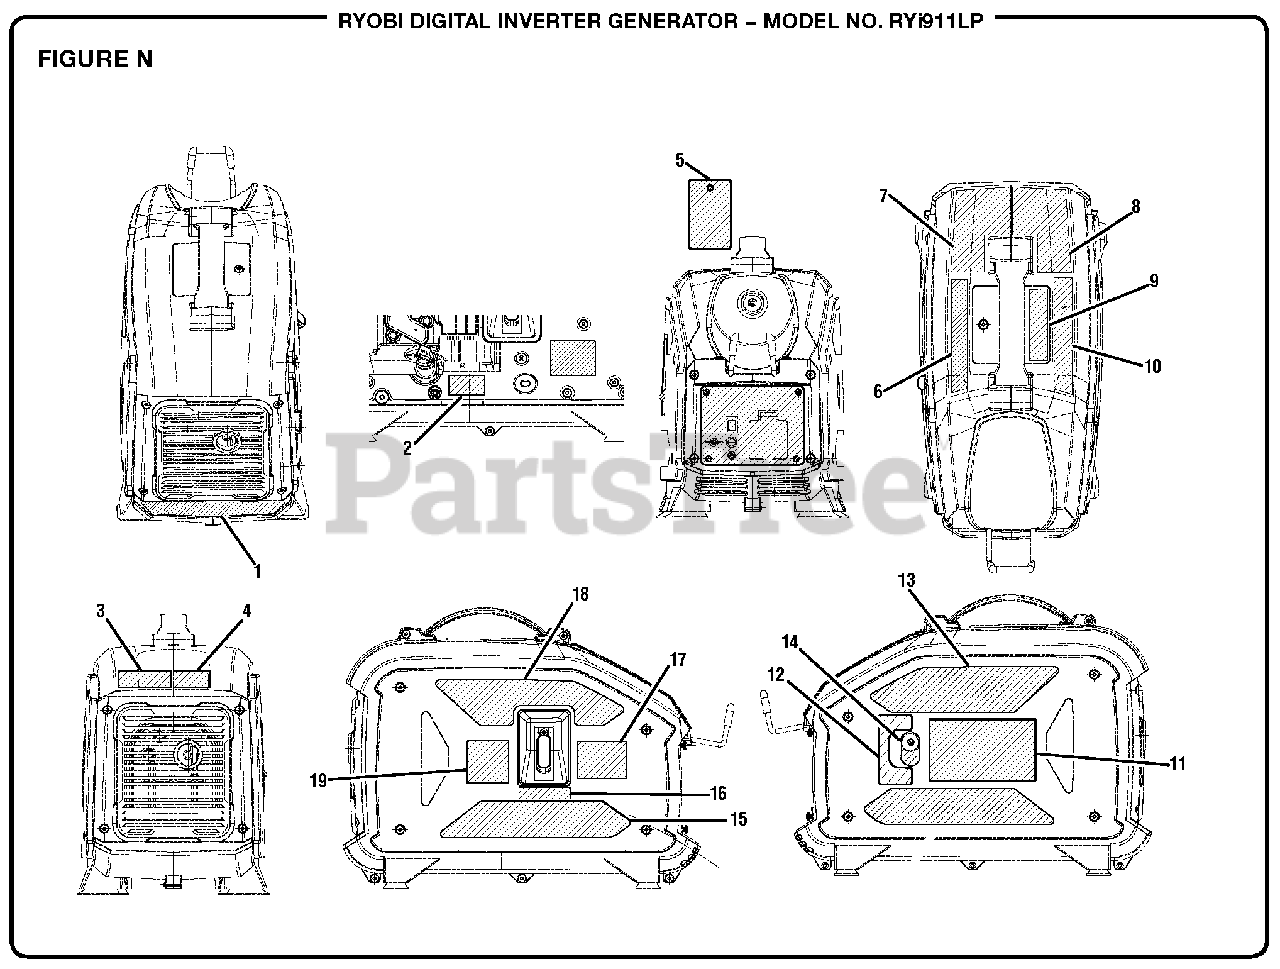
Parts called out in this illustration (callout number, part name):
1	Combustion Label
2	Maintenance Label
3	Hot Surface Label (English/Spanish)
4	Hot Surface (French)
5	Warning Hangtag
6	Storage Tips Label
7	CPSC Label (English)
8	CPSC Label (French/Spanish)
9	Inquiries Label
10	Starting Instructions Label
11	LP Warning Label
12	Primer Button Label
13	Fire Distance Label
14	Primer Button
15	Performance Label (Bottom)
16	Primer Reminder Label
17	Logo Label
18	Performance Label (Top)
19	Lubricant Label
